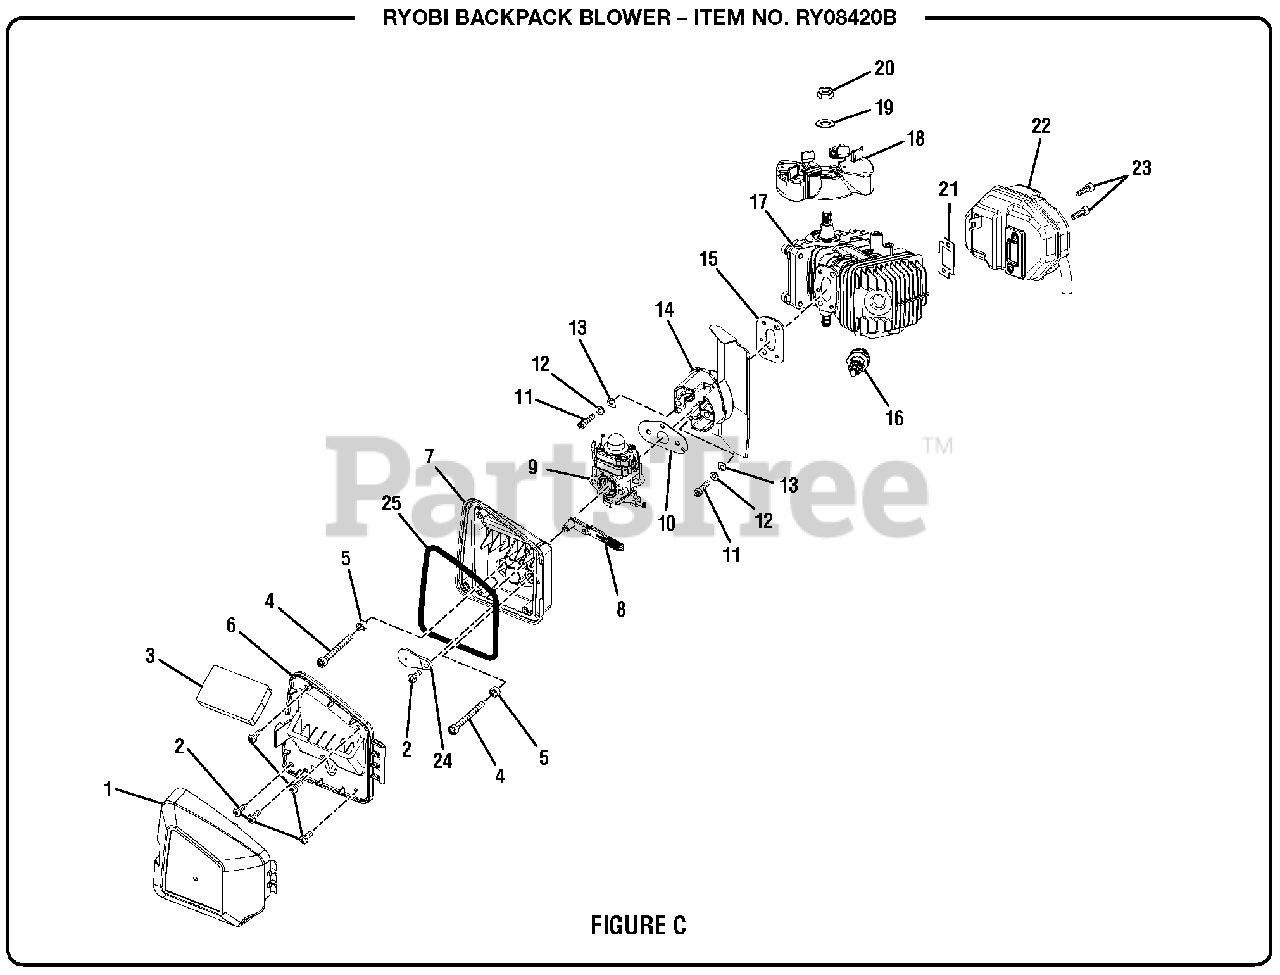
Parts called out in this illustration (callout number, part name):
1	Air Box Cover
2	Screw (M4 x 12 mm, T20 Torx Pan Hd.)
3	Air Filter
4	Screw (M5 x 50 mm, Soc. Hd.)
5	Washer (ID5.8 x OD11.5 x 1.7t)
7	Air Box Base
8	Choke Lever
9	Carburetor (Walbro, WYJ-536)
10	Gasket Carb-Heat Dam
11	Screw (M5 x 0.8 in.)
12	Spring Washer (M5)
13	Washer (Heat Dam)
15	Heat Dam Gasket
16	Spark Plug (RCJ4)
17	Short Block Assembly
18	Flywheel Assembly
19	Washer (ID9 x OD17.7 x 1.1t)
20	Lock Nut (M8)
22	Exhaust Assembly
23	Bolt (1/4-20 x 18 mm)
24	Choke Plate
25	Airbox Gasket
